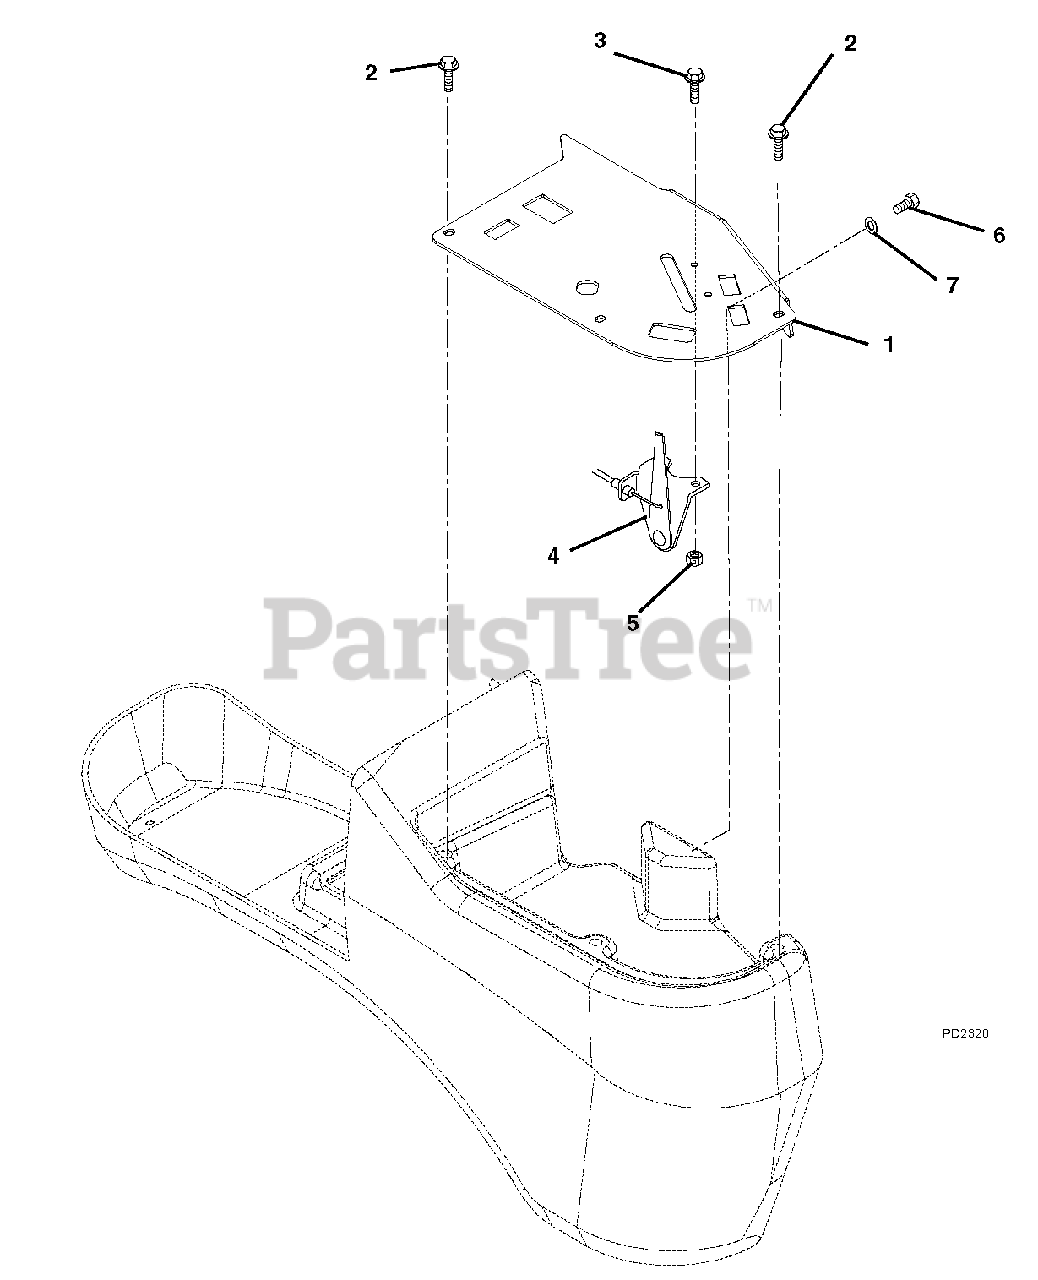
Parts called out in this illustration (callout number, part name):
1	Panel, Control
2	Screw, Machine 10-24 x .50 Hex Washer Head, Stainless
3	Screw, Machine 10-24 x .75 Hex Washer Head
4	Throttle, Control
5	Nut, Locking Nylon 10-24 With Insert
6	Bolt-Hex .31-18 x .75 Grade 5
7	Washer-Flat-Steel .38 x .875 x .083
